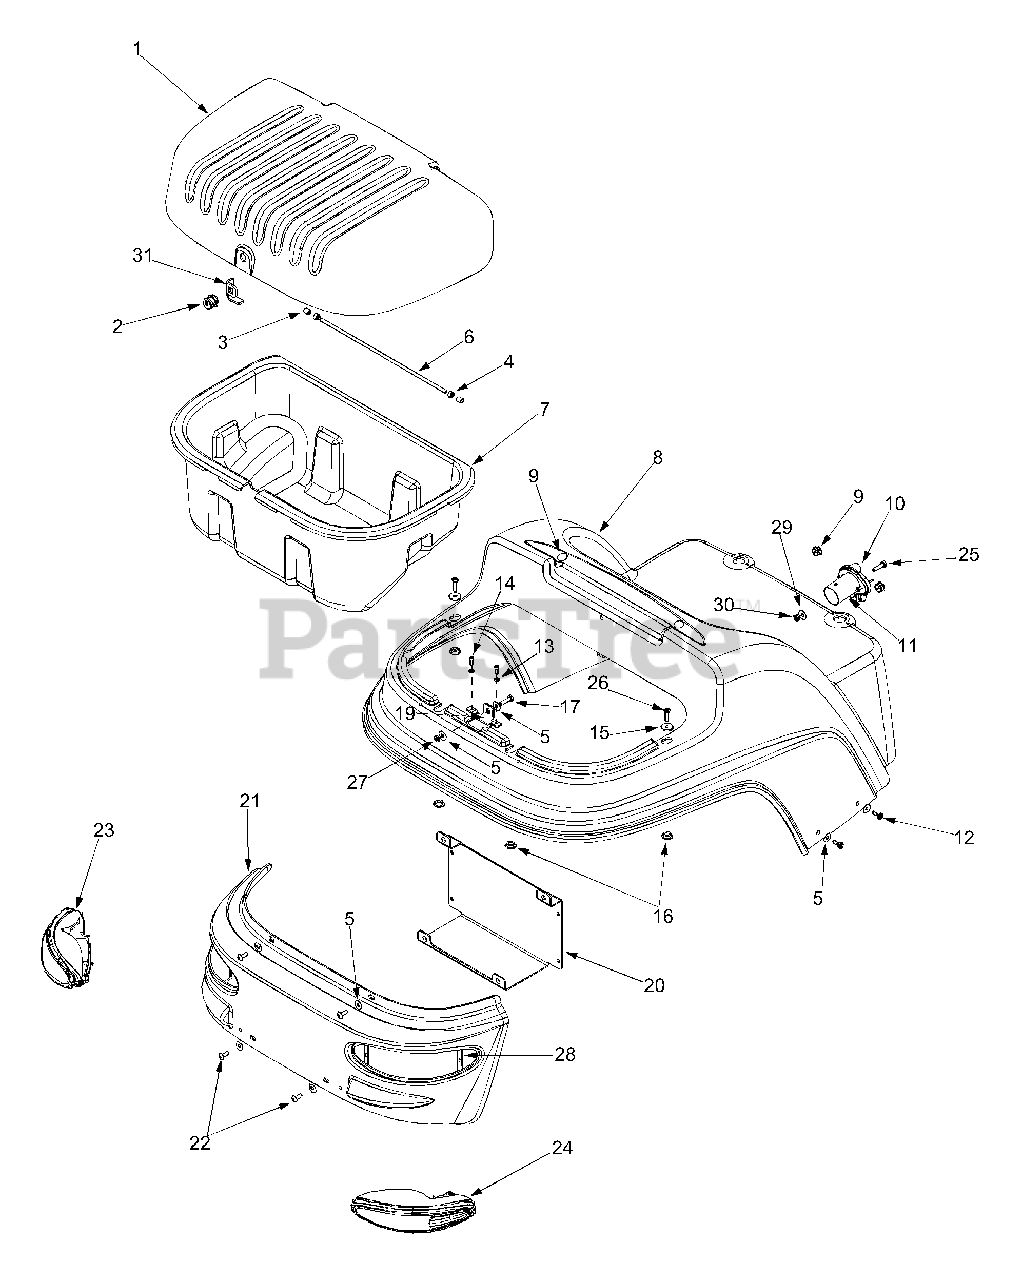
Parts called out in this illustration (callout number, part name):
1	Trunk Lid - Silver
2	Trunk Key Lock
3	Sleeve Bearing
4	Shaft Collar
5	Flat Washer .260 ID x .720 OD
6	Trunk Hinge Rod
7	Trunk Basket Panel
8	Rear Panel - Silver
10	Plug Housing
11	Plug Cover
12	Quick Opening Captive Screw
13	Flat Washer .203 ID x .403 OD
14	Screw 10-32 x .5
15	Flat Washer .265 ID x .938 OD
16	Shoulder Spacer .380 ID x .620 OD
17	Cap Screw 1/4-20 x 1.0
19	Trunk Mounting Plate
20	Rear Bumper Bracket
21	Rear Bumper Panel
22	Screw 1/4-20 x .750
23	Taillight Assembly - LH
24	Taillight Assembly -RH
25	Slotted Hex Screw #10 -32
26	Screw 1/4-20 x 1.0
27	Jam Nut 1/4-20
28	Taillight Clip
29	Flat Washer .281 ID x .50 OD
30	Hex Nut #10-32
31	Trunk Lock
